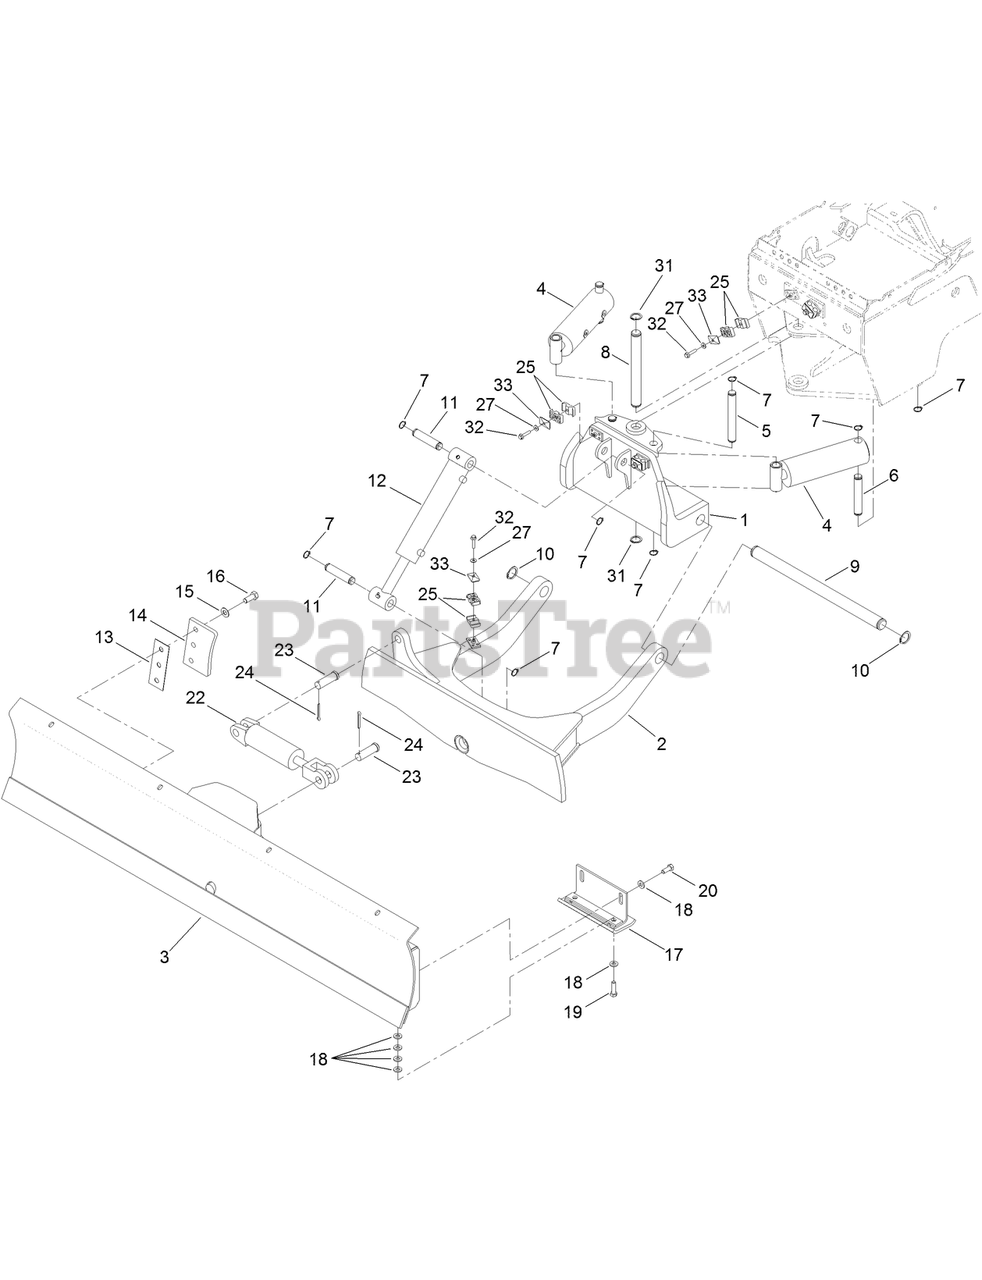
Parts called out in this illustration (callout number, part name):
1	PIVOT-BACKFILL
4	HYD CYLINDER ASM
5	PIN-LINK
6	PIN-LINK
7	RING-RETAINING
8	PIN-Pivot
9	PIN-FRAME
11	PIN-CYLINDER
13	SHIM-RETAINER
14	RETAINER-BLADE
15	WASHER-FLAT
16	SCREW-HH
17	SHOE-SKID
18	WASHER-FLAT
19	SCREW-HH
20	SCREW-HH
22	HYD CYLINDER ASM
23	PIN-HEADED
24	PIN-COTTER
25	CLAMP-TUBE
27	WASHER
31	RING-RETAINING
32	SCREW-HHF
33	COVERPLATE
